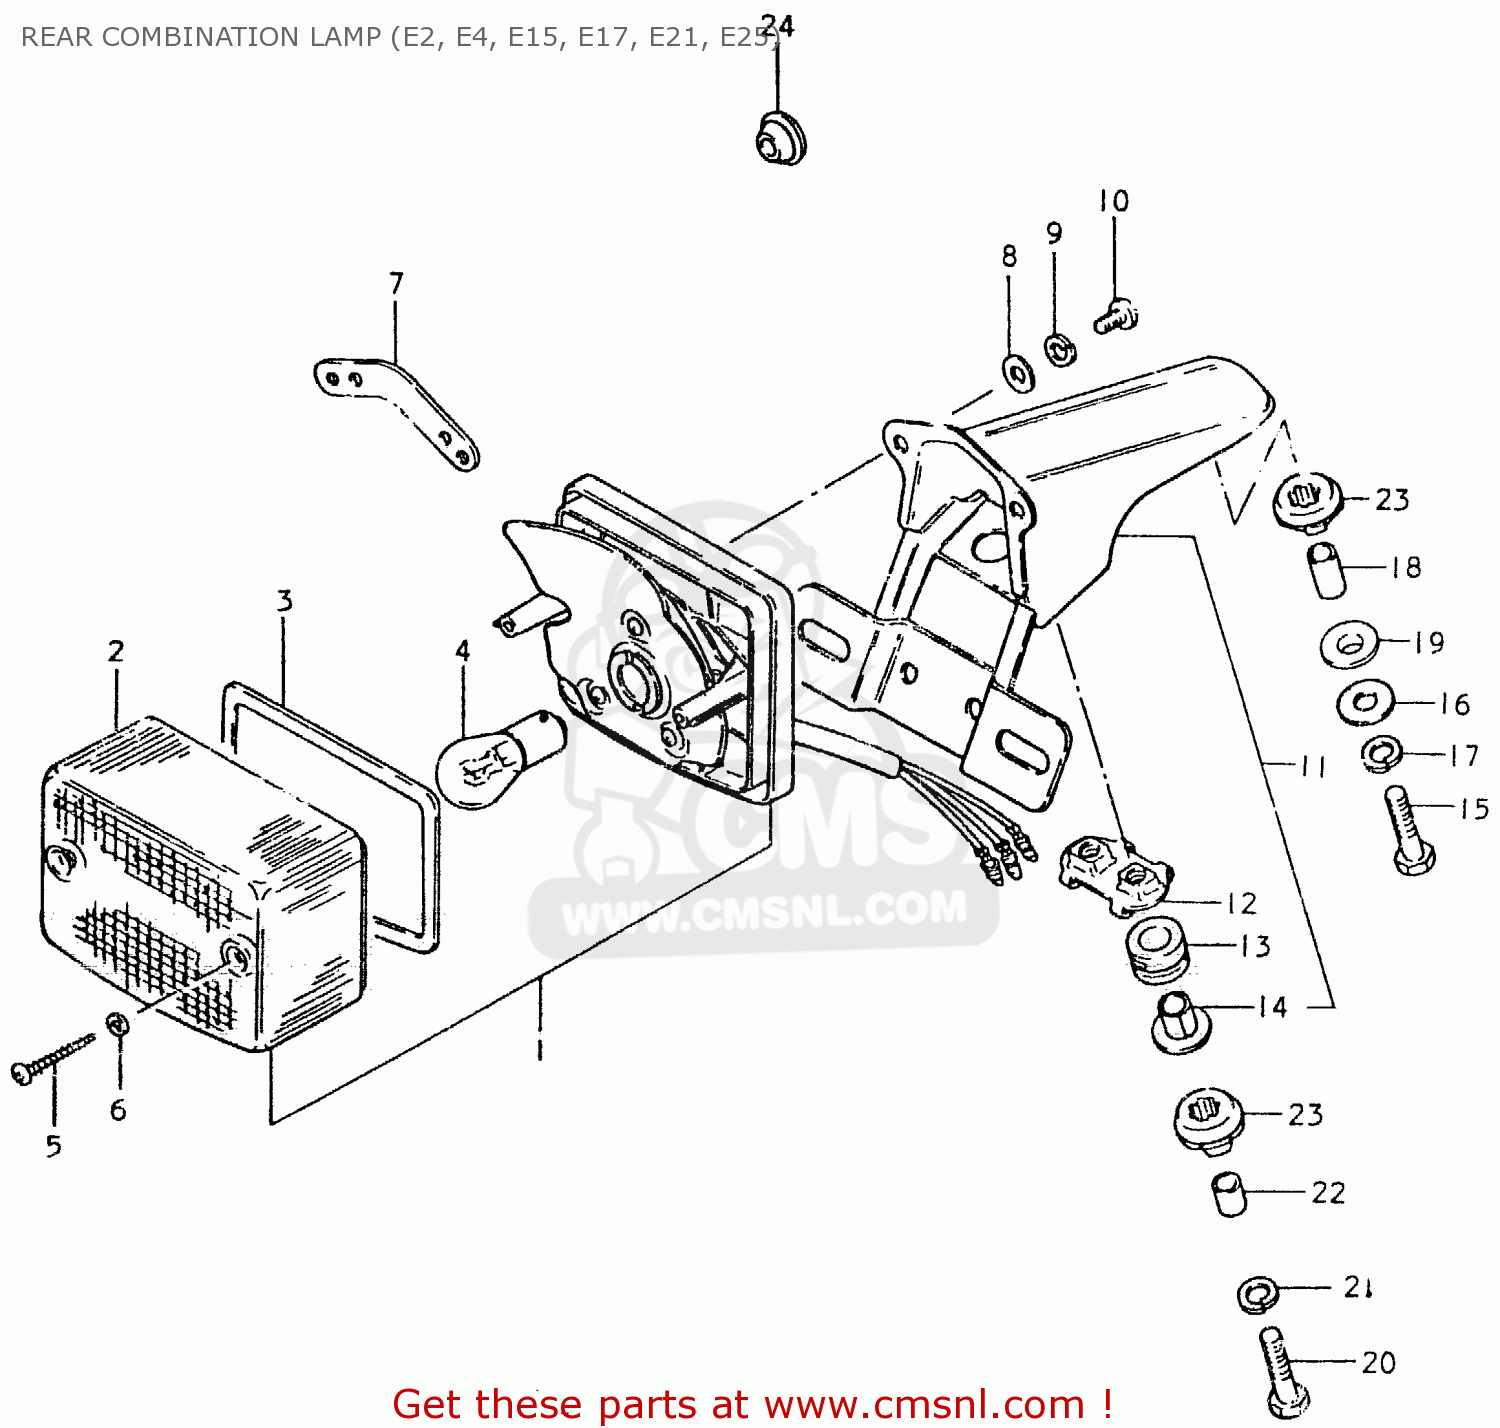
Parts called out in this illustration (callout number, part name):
1	LAMP UNIT, TAIL
2	LENS
3	GASKET (NAS)
4	BULB (6V,21/5W)
5	BOLT
6	GASKET (NAS)
7	PLATE,REAR COMBINATION LAMP
8	WASHER
9	LOCK WASHER
10	SCREW
11	BRACKET ASSY
12	PLATE
13	CUSHION
14	SPACER
15	BOLT
16	WASHER (6.5X20X1.2)
17	LOCK WASHER
18	SPACER
19	CUSHION
20	BOLT
21	LOCK WASHER
22	SPACER (6.8X10X11.5)
23	CUSHION
24	GROMMET
